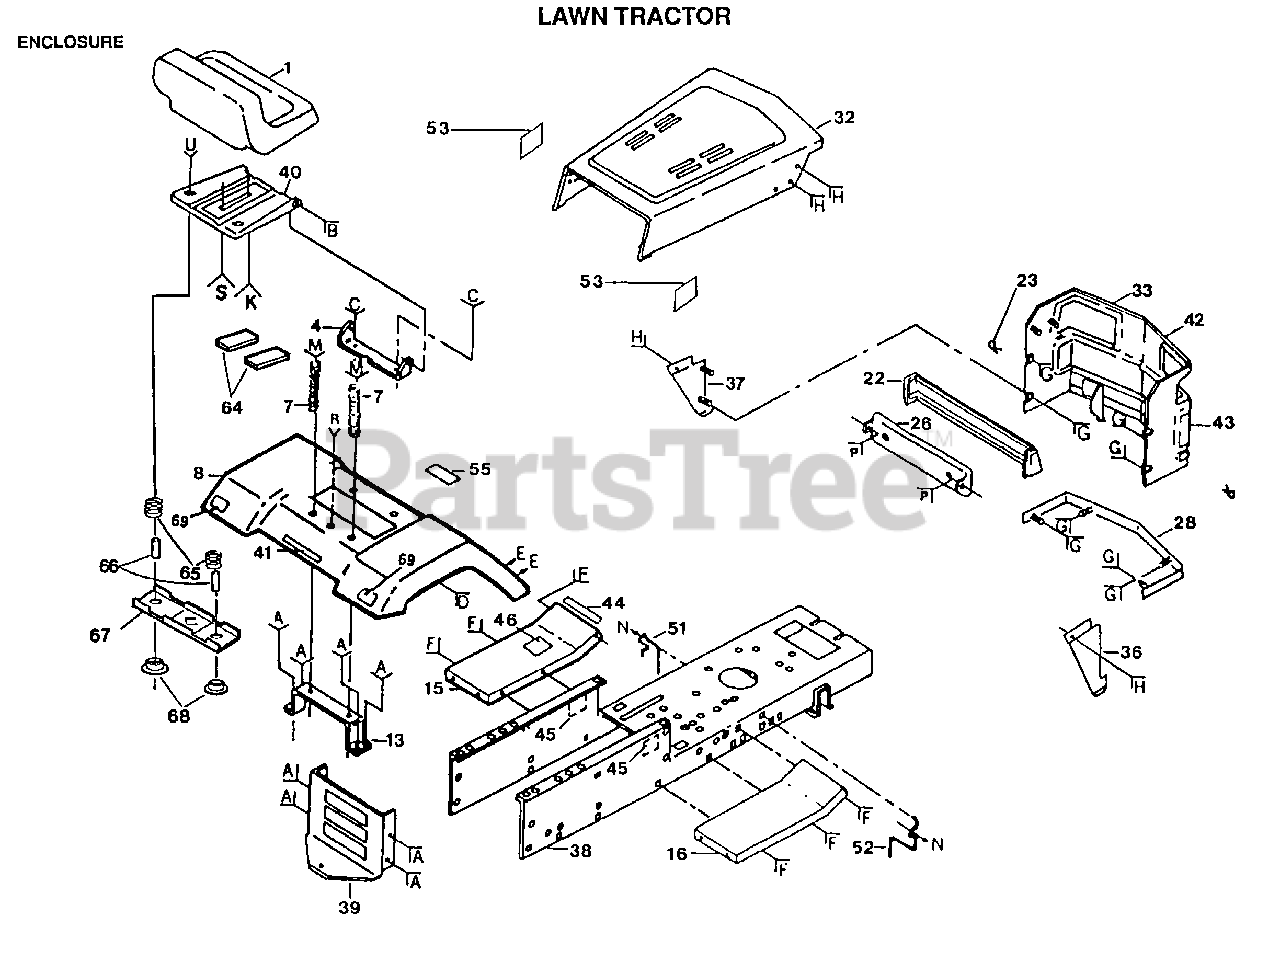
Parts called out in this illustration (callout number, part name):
7	SPRING COMPRESSIO
15	FOOTREST LH
16	FOOTREST
38	CHASSIS ASS'Y
44	DECAL T
45	DECAL, CHASSIS, SPEED/DECK SIZE
51	BELT GUIDE
52	BELT GUIDE
64	STRIP FORM
65	SPRING
66	SPACER SPLIT
67	BRKT SWITCH
68	BUSHING
69	REFLECTOR-TAIL YT
